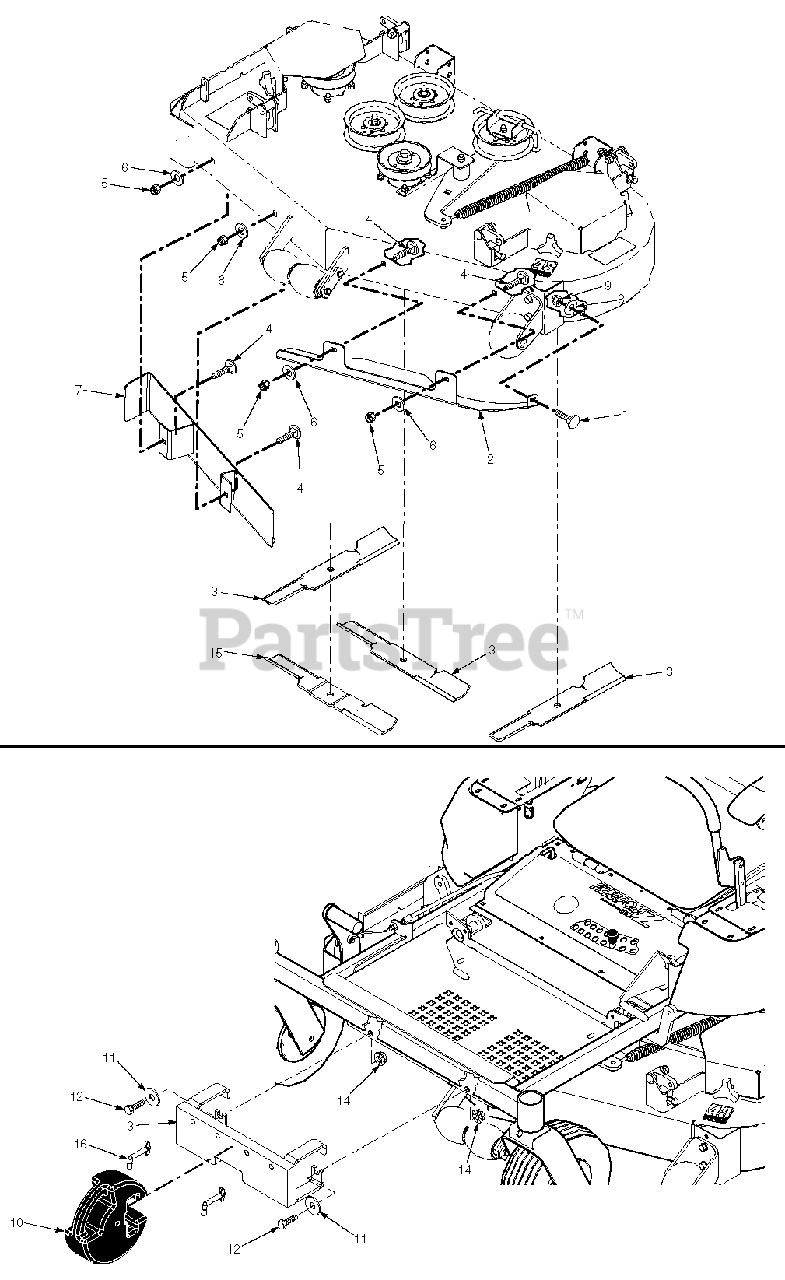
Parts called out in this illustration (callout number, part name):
1	Bolt, Carriage 5/16-18 x 3/4"
2	Baffle, LH - 48" Deck
2	Baffle, LH -52" Deck
2	Baffle, LH - 61" Deck
3	Cutter Blade, High Lift (36" Deck)
3	Cutter Blade, High Lift (48" Deck)
3	Cutter Blade, High Lift (52" Deck)
3	Cutter Blade, High Lift (61" Deck)
4	Bolt, Carriage 3/8-16 x 1"
5	Nut, Elastic Stop 3/8-16
6	Flatwasher, 3/8-.438 x 1.00 x .083
7	Baffle Weldment,RH - 36" Deck
7	Baffle Weldment, RH - 48" Deck
7	Baffle Weldment, RH - 52" Deck
7	Baffle, Weldment, rh - 61" Deck
8	Flatwasher, 5/16-.344 x .688 x .065
9	Nut, Center Lock 5/16-18
10	Weight Assembly
11	Flatwasher, 1/2-.562 x 1.375 x .109
12	Bolt, Hex Head 1/2-13 x 1-1/4"
13	Support Weldment, Weight Mounting
14	Nut, Serrated Flange 1/2-13
15	Cutter Blade, Cross - 36" & 52" Deck
15	Cutter Blade, Cross - 48" Deck
15	Cutter Blade, cross - 61" Deck
16	Pin, Weight Retention
